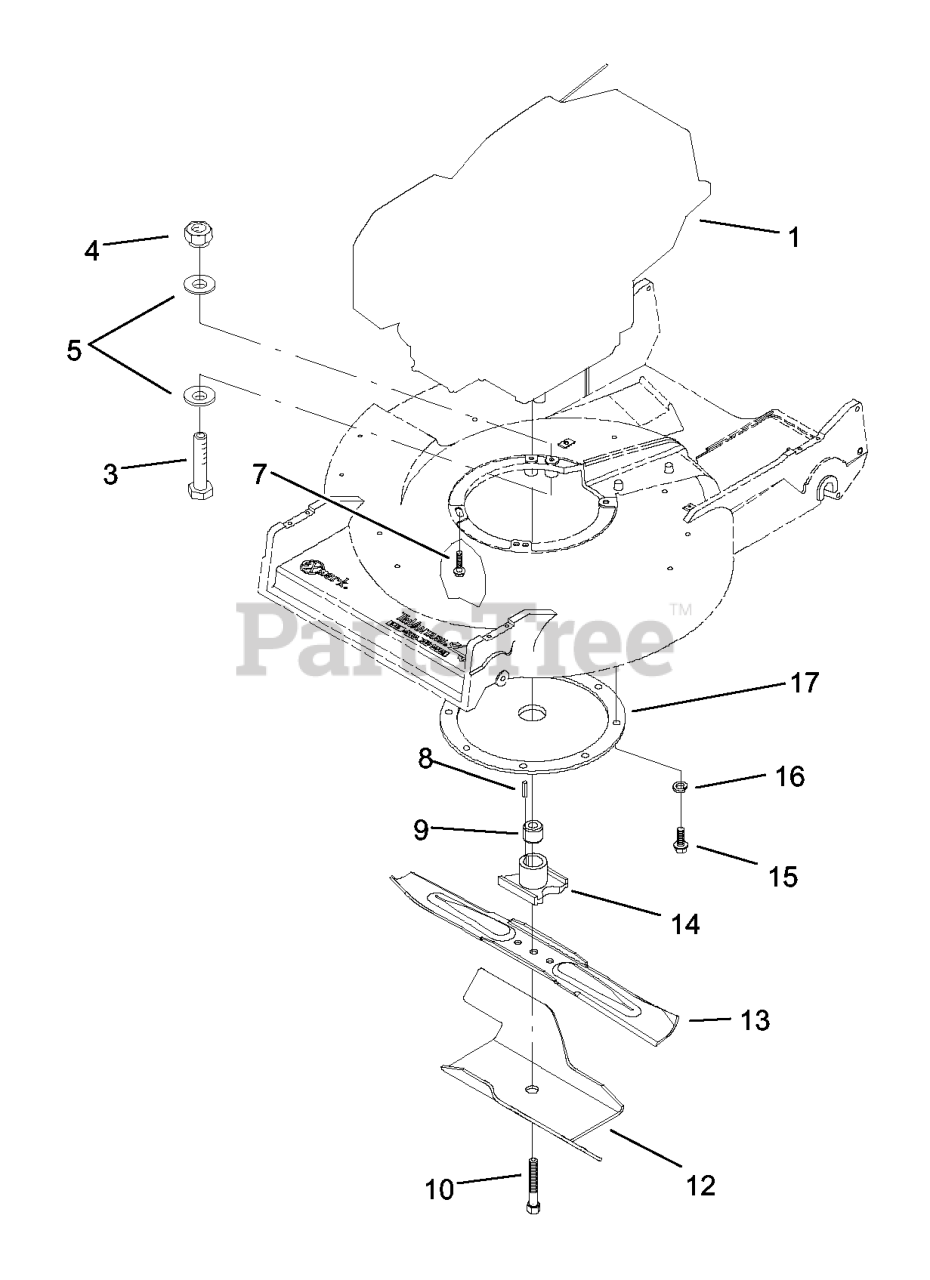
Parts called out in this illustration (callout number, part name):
3	SCREW-HH
4	NUT-LOCK, NI
5	WASHER-PLAIN
7	SCREW-SHOULDER
8	KEY-SQUARE
9	SPACER-RETAINER, BLADE
12	STIFFENER-BLADE
14	RETAINER-BLADE
15	Screw-HWH 5/16-18 X 3/4 Tf
16	WASHER-LOCK, INTERNAL
17	PROTECTOR-CRANKSHAFT
